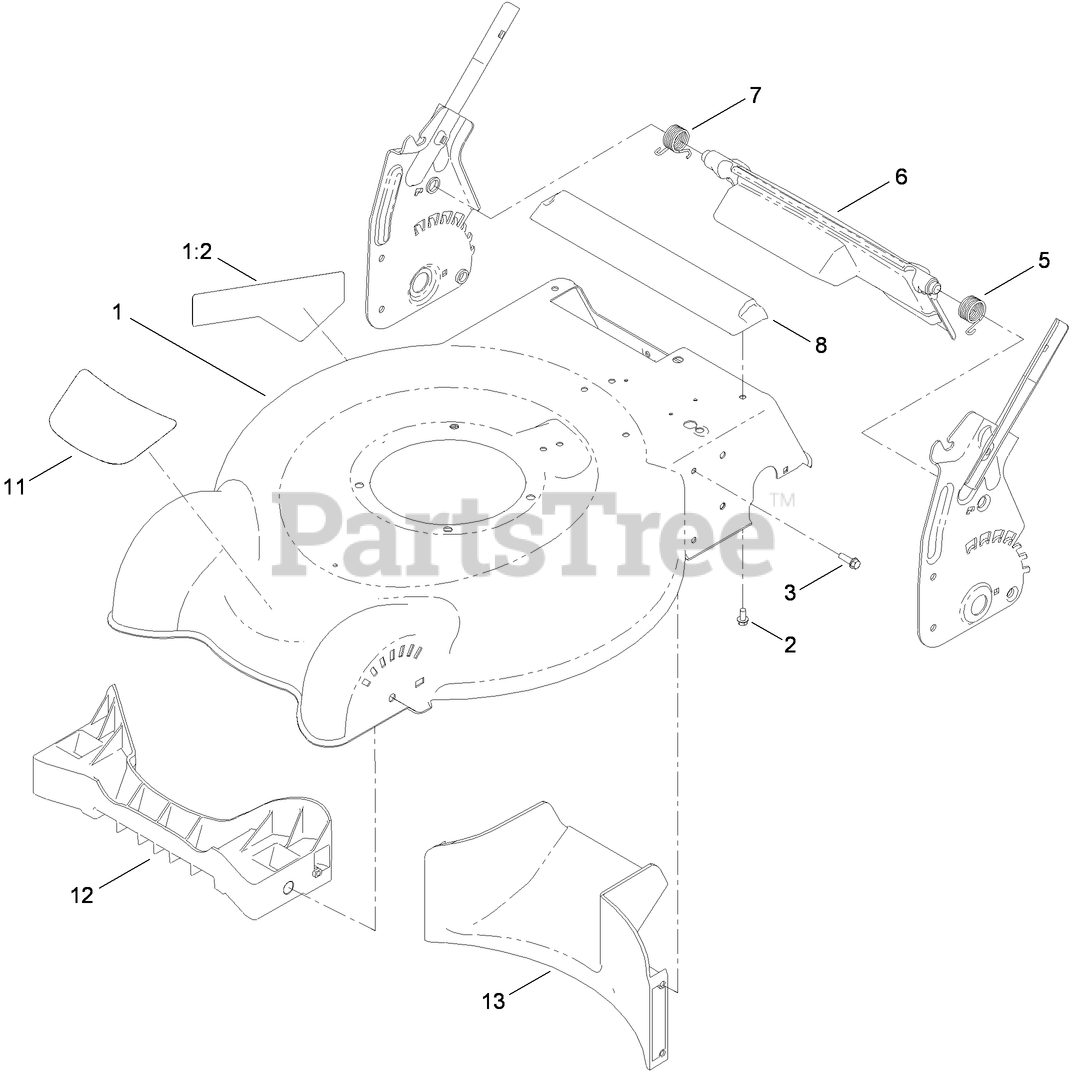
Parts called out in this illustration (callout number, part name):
1	ELECTRIC HOUSING ASM
1:2	DECAL-DANGER
2	SCREW-PLASTITE
3	SCREW-HWH
5	SPRING-TORSION, LH
6	DEFLECTOR-REAR
7	SPRING-TORSION, RH
8	CHUTE-REAR
11	DECAL-BATTERY
12	BAFFLE-FRONT
13	BAFFLE-REAR
